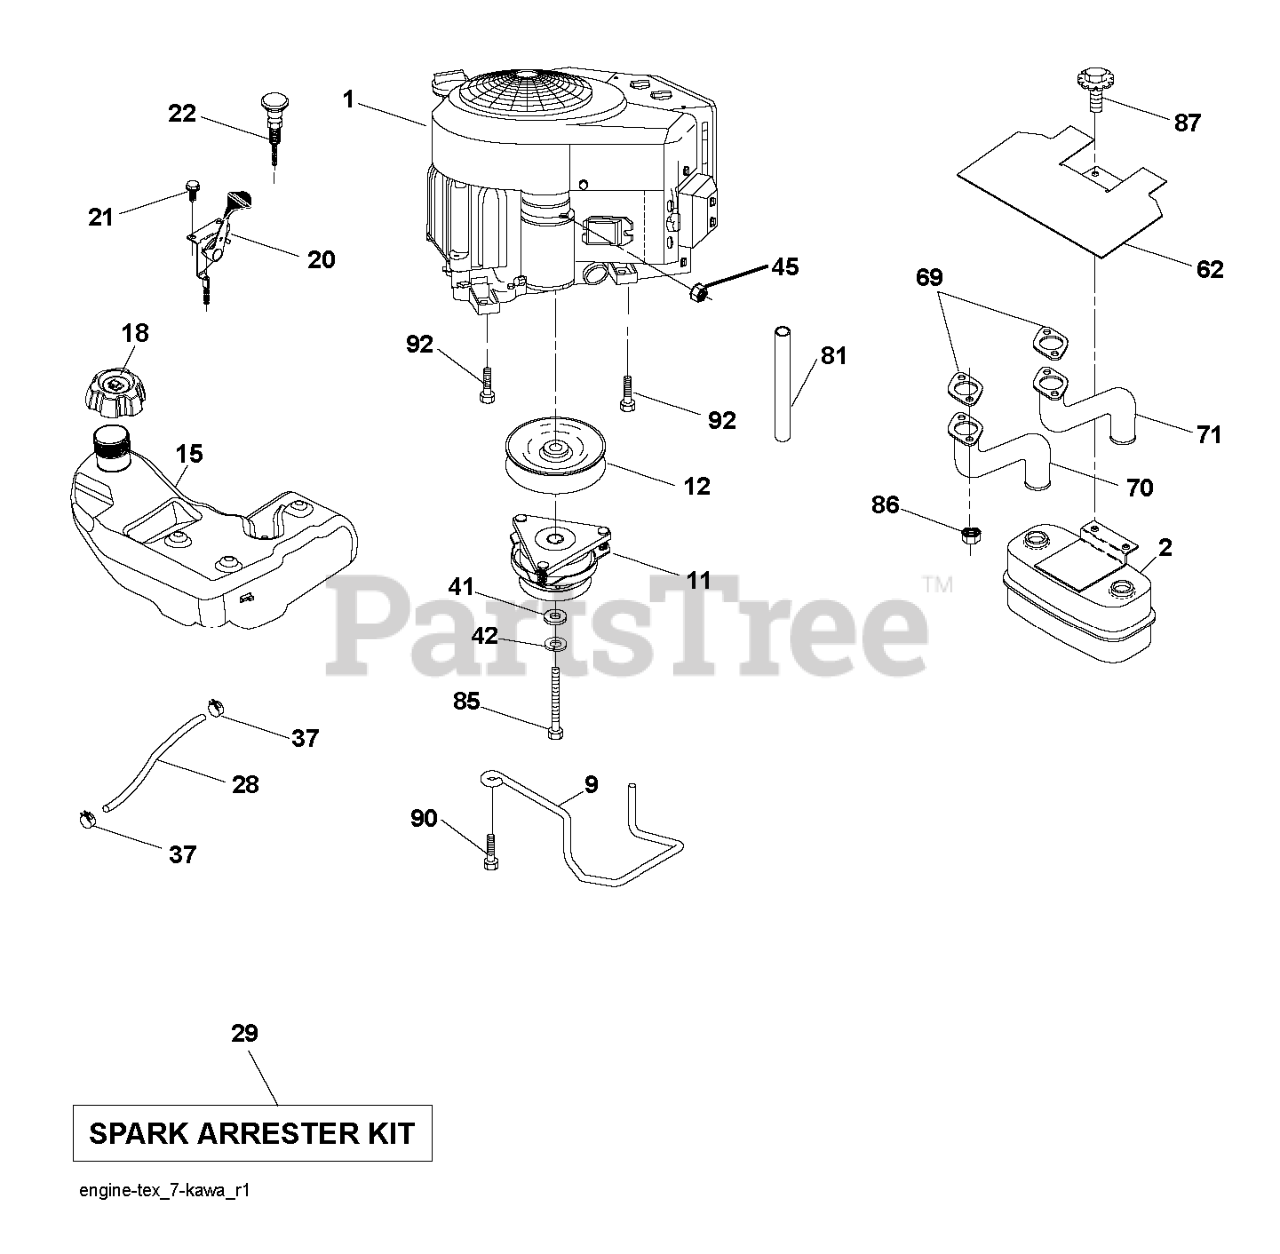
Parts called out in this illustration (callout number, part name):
2	MUFFLER.TWIN.CYL.LOW.TONE
9	KEEPER.BELT.ENGINE.4.2
11	RB.CLUTCH.OGURA.4.4.PD
12	PULLEY.ENGINE.TUFFTORQ
15	TANK.FUEL.4GAL
18	CAP.FUEL.TANK.3"GREY
20	THROTTLE CABLE
21	SCREW.#10 X 0.750.BOS
22	CONTROL.CHOKE.ERGO.PUSH-IN.BLA
28	REPL BY 532 00 85-43
29	KIT.SPARK ARRESTOR 794945 B&S
37	HOSE CLAMP
42	LOCKWASHER
45	NUT
62	RP SHIELD HEAT MUFFLER
69	GASKET.EXHAUST.KAWASAKI.15-1
70	EXHAUST TUBE LH KAWI
71	EXHAUST TUBE RH KAWI
81	TUBE, DRAIN OIL ASM.
85	BOLT HEX 7/16-20X4-1/4"
86	NUT.HEX.FLANGE.TOPLOCK
87	BOLT.5/16-18UNCX3/4 W/SEMS.BLK
90	SCREW 3/8-16X1
92	SCREW 3/8-16X1
